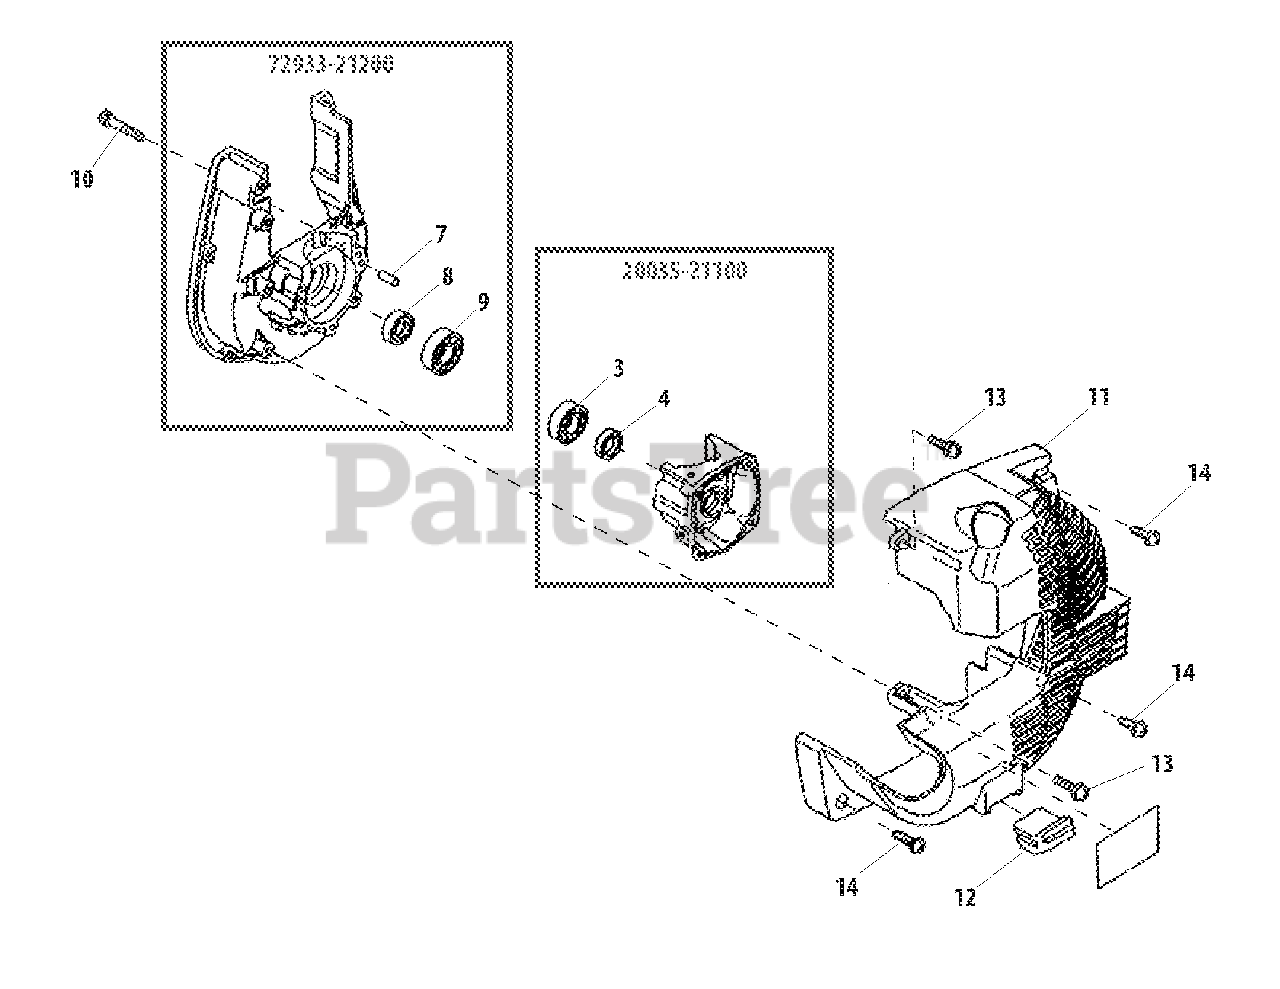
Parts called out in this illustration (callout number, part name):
3	BEARING, BALL 6001 C3
4	SEAL, OIL 12
7	PIN, LOCATING Ø4×8
8	SEAL, OIL 12
9	BEARING, BALL 6201C3
10	BOLT 5×25
11	COVER, ENGINE
12	CUSHION
13	SCREW
14	SCREW 5×20
20035-21100	CRANKCASE ASSY
72933-21200	CRANKCASE ASSY, M
